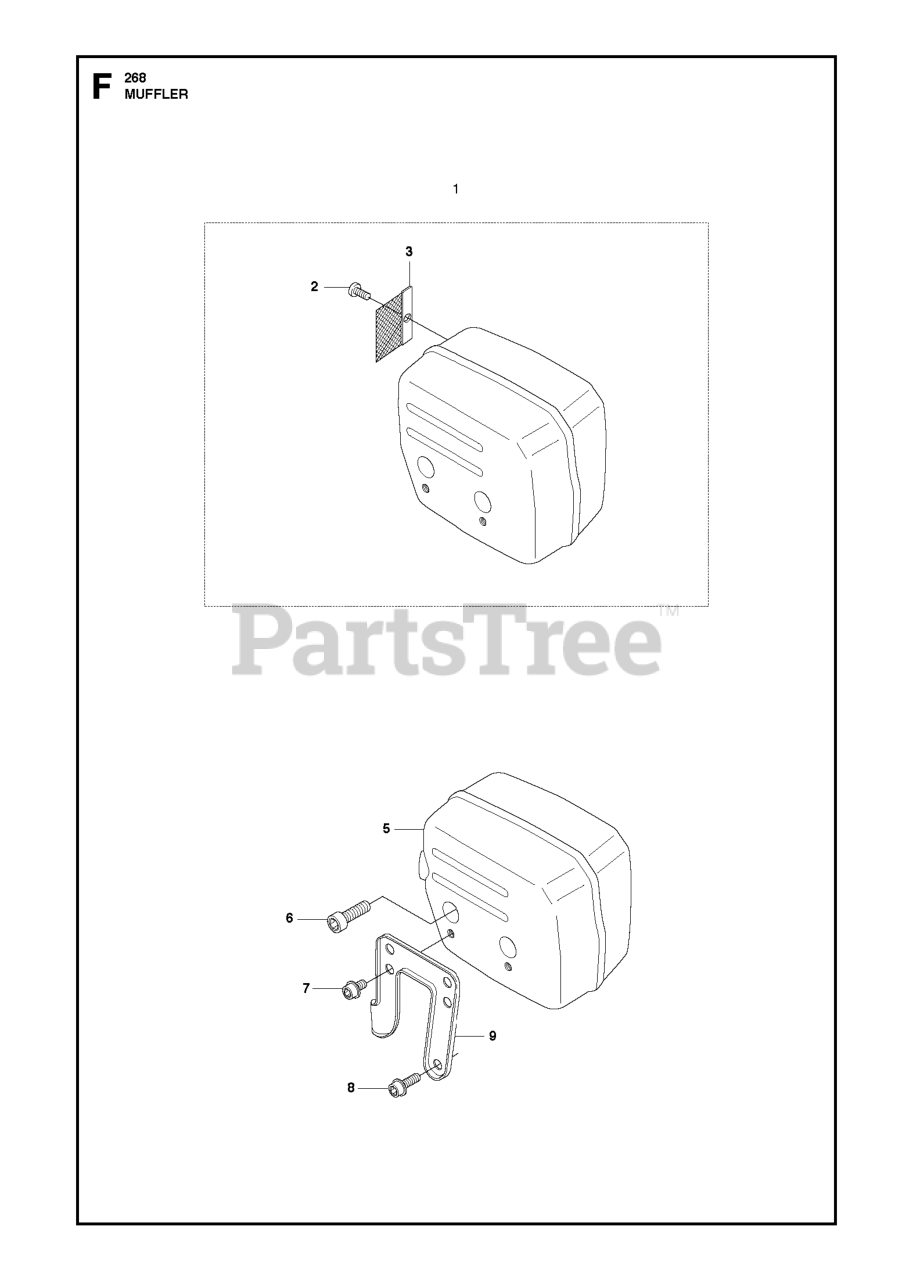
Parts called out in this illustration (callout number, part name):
1	MUFFLER
5	MUFFLER
6	SCREW MC6S 6X20
7	SCREW
9	SUPPORT
